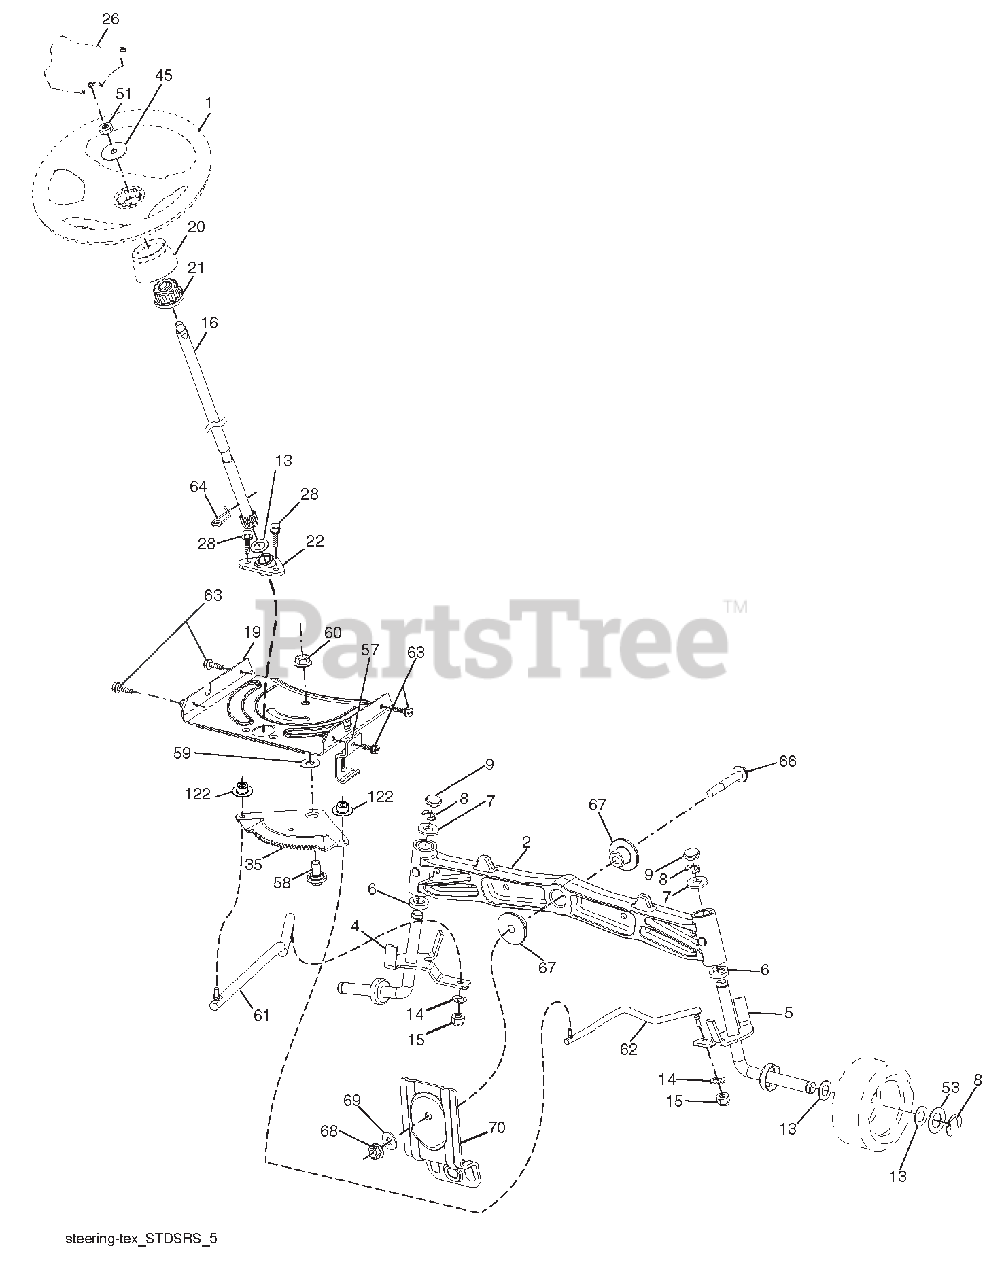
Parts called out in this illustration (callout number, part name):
1	WHEEL STEERING
2	AXLE.CAST IRON
4	SPINDLE.WELDED.LH.15"TEX
5	SPINDLE.WELDED.RH.15"TEX
6	WAHSER THRUST .75 X 1.230
7	WASHER.25/32 X 1-5/8 X 16GA.
8	RING.KLIP.#T5304-75
9	CAP.SPINDLE.FR.TOP.BLK.
13	WASHER.25/32 X 1 1/4 X 16 GA.
14	Washer, Lock 3/8
15	NUT.CROWNLOCK.3/8-24
16	SHAFT.STEER.3/4 TEX.NON-PLATED
19	PLATE.STEER.DDL.NLT/NGT
20	BOOT.STEERING
21	ADAPTER.WHEEL.STRG..760
22	STEERING SUPT. LOWER
26	CAP WHEEL STEERING HRS/SRS BLK
28	SCREW.HEXWSH THDR3/8-16X3/4.BL
35	GEAR SECTOR.PLATE.DDL.NLT/NGT
45	WASHER.9/16ID X 2-3/8OD.12GZIN
51	NUT.HEX.JAM.TOPLOCK.1/2-20 UNF
53	WASHER.HARDEN..793 X 1.637X060
57	BRACKET.UPSTOP.GT/LT.TEX
58	BOLT.SHOULDER.SECTOR.PIVOT.CFM
59	WASHER.THRUST.SECTOR.STEER.NLT
60	NUT.FLANGE LOCK.5/8-11
61	DRAGLINK.LH.BALLSTUD.DDL.
62	DRAGLINK.RH.BALLSTUD.DDL
63	SCREW.5/16-18X3/4.SMGML.TAP/BL
64	RETAINER.CLIP.SPRING.STEERING
66	BOLT.HEX.FGHD.7/16-14 X 3.SERR
67	BUSHING.PM.FRONT AXLE
68	NUT.LOCK.FLANGE.7/16-14.GR5
69	WASHER.1.5 X .505 X .118
70	BRACKET.DECK.SUSPENSION.FRONT
122	CAP GEAR SECTOR
